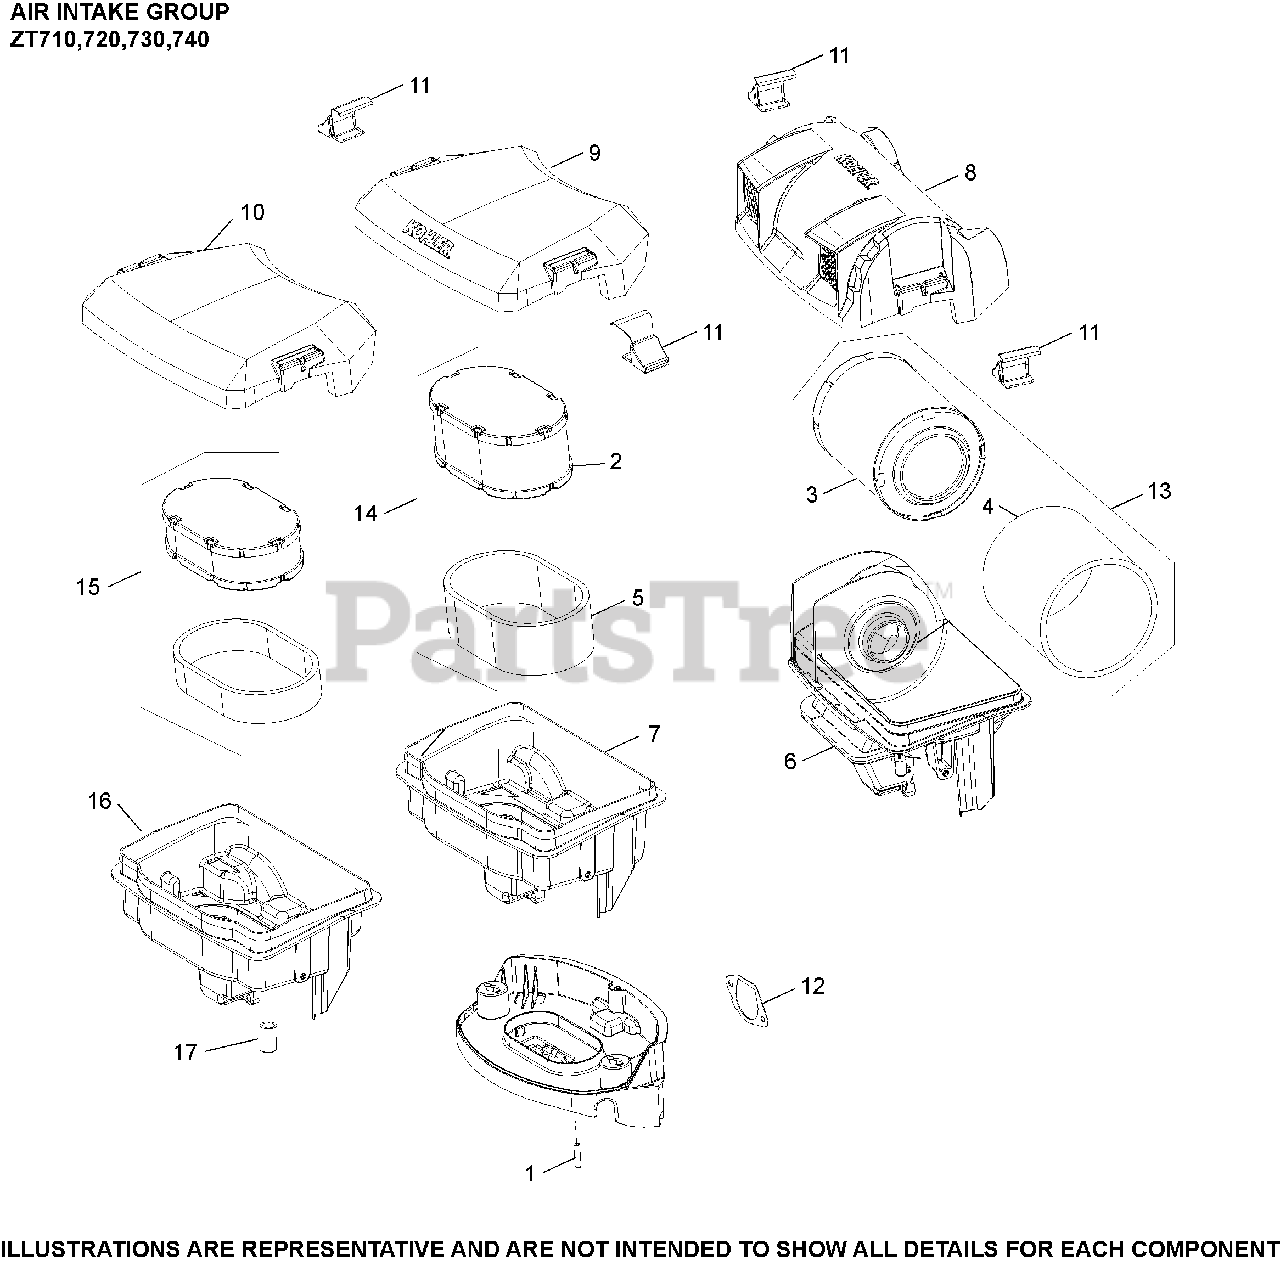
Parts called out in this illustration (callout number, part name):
1	CAP, MASKING
3	ELEMENT, AIR FILTER - Also available Retail Packaged 16 883 01-S1 Air Filter Kit
4	ELEMENT, PRE-CLEANER
6	BASE ASSEMBLY, AIR CLEANER (HDAC) USE 16 094 09-S
8	COVER, AIR CLEANER (HDAC)
11	LATCH ASSY, AIR CLEANER COVER
12	GASKET, AIR CLEANER BASE
